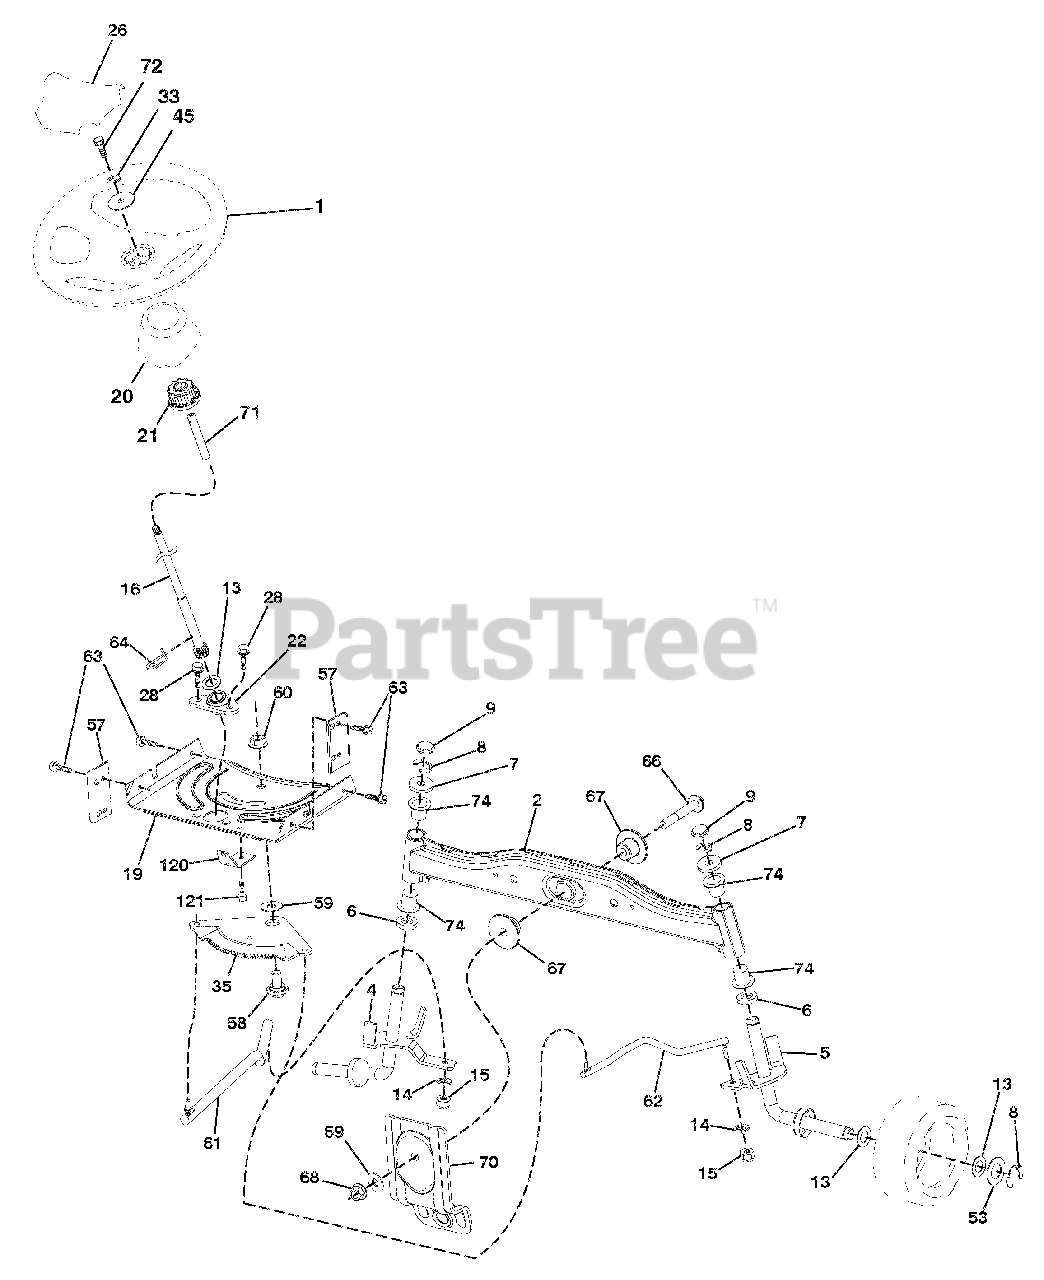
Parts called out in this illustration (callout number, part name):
1	WHEEL.STEERING.HARD RIM.BLACK
2	AXLE ASM.WELDED
4	SPINDLE.WELDED.LH.15"TEX
5	SPINDLE.WELDED.RH.15"TEX
6	WASHER.THRUST..75 X 1.230
7	WASHER.25/32 X 1-5/8 X 16GA.
8	RING.KLIP.#T5304-75
9	CAP.SPINDLE.FR.TOP.BLK.
13	WASHER.25/32 X 1 1/4 X 16 GA.
14	Washer, Lock 3/8
15	NUT.CROWNLOCK.3/8-24
16	SHAFT.STEER.3/4 TEX.NON-PLATED
19	PLATE.STEER.DDL.NLT/NGT
20	BOOT.STEERING.LT.TEX P/L.428
21	ADAPTER.WHEEL.STRG..760
22	STEERING SUPT.LOWER
26	CAP.WHL.STRG.HRS/SRS.BLACK
28	SCREW.HEXWSH THDR3/8-16X3/4.BL
33	Washer, Lock 5/16
35	GEAR SECTOR.PLATE.DDL.NLT/NGT
45	WASHER.11/32ID X2 3/8OD X 12GA
53	WASHER.HARDEN..793 X 1.637X060
57	BRACKET.UPSTOP.TEX
58	BOLT.SHOULDER.SECTOR.PIVOT.CFM
59	WASHER.THRUST.SECTOR.STEER.NLT
60	NUT.FLANGE LOCK.5/8-11
61	DRAGLINK.LH.BALLSTUD.DDL.
62	DRAGLINK.RH.BALLSTUD.DDL
63	SCREW.5/16-18X3/4.SMGML.TAP/BL
64	RETAINER.CLIP.SPRING.STEERING
66	BOLT.HEX.FGHD.7/16-14 X 3.SERR
67	BUSHING.PM.FRONT AXLE
68	NUT.LOCK.FLANGE.7/16-14.GR5
69	WASHER.1.5 X .505 X .118
70	BRACKET.DECK.SUSPENSION.FRONT
71	SHAFT.EXTEN.STRG.SPLINE.TEX
72	BOLT.FIN.HEX.5/16-18 UNC X 4 W
74	BEARING.COL.STRG.BLK.
120	BRACKET LOCATER CBL.BRK.
121	SCREW.THDROL.5/16-18 X 1/2TYTT
